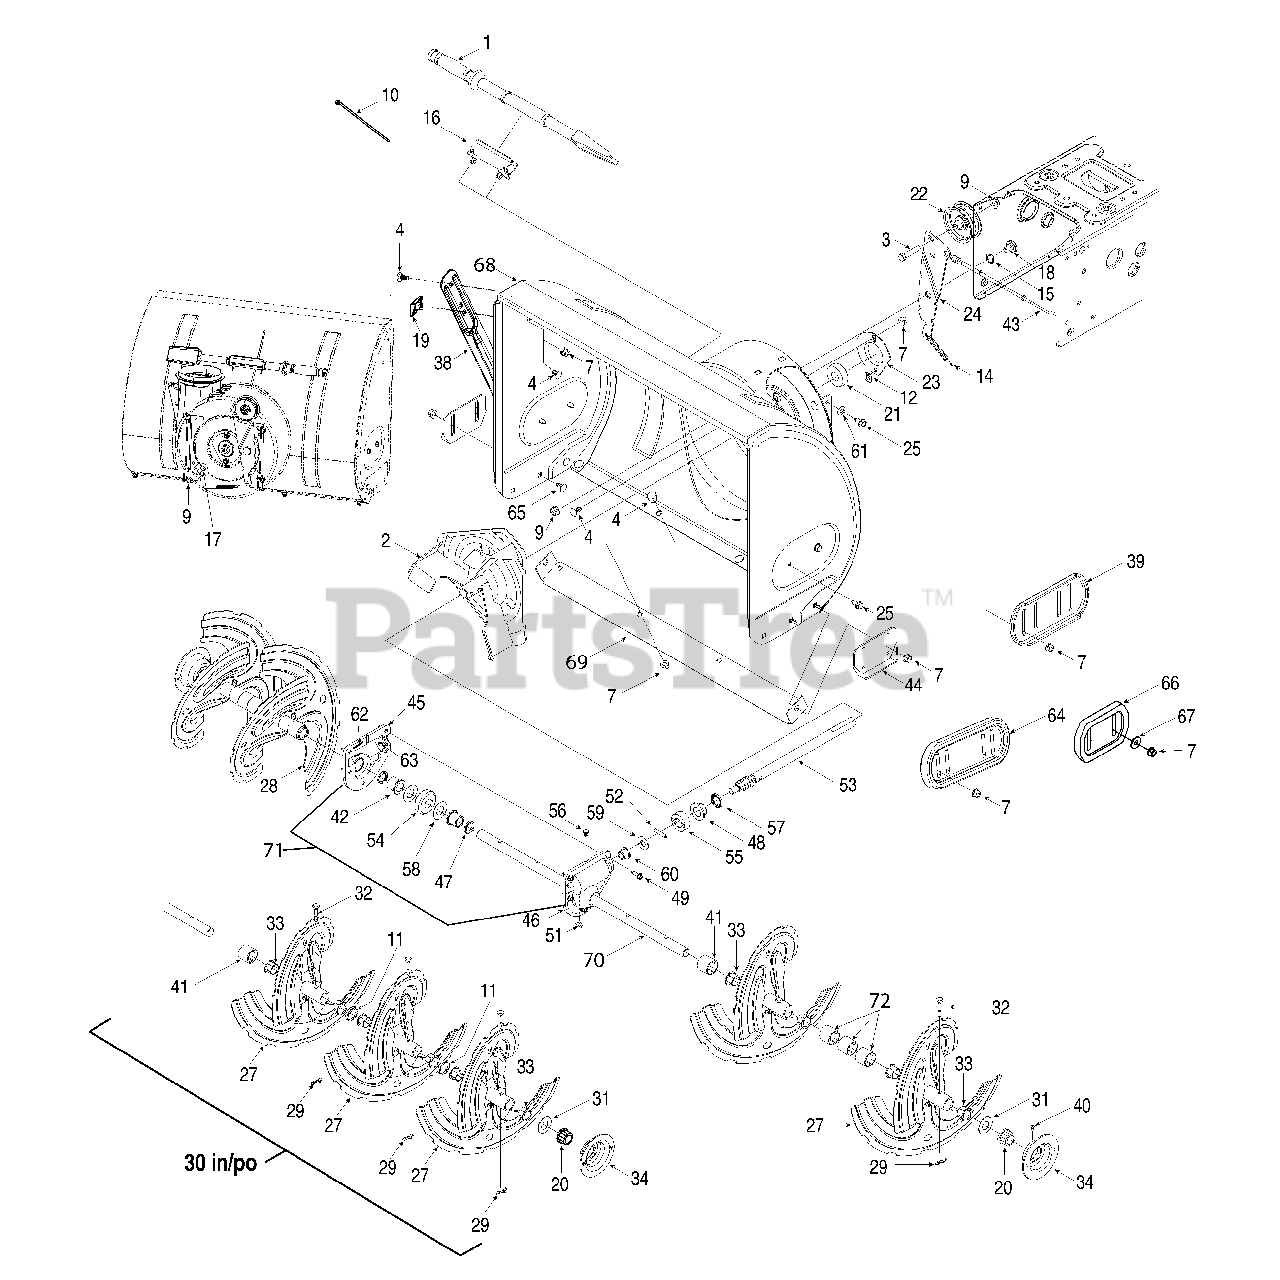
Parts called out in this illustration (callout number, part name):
1	Clean-Out Tool
2	Impeller Ass'y
3	Hex Screw 3/8-16 x 1.75
4	Carriage Bolt 5/16-18 x .75
7	Flange Locknut 5/16-18 Gr. F Nylon
9	Hex L-Flanged Nut 3/8-16 Gr. F Nylon
10	Cable Tie
11	Spacer 1.25 x .75 x 3/16" Lg.
12	Push-on Nut .25 dia.
14	Extension Spring .38 OD x 4.59" Lg.
15	Wave Washer .660 ID x .88 OD x .010
16	Cleanout Tool Mount
17	Shld. Scr. .500 Dia. x .335" Lg.
18	Shoulder Scr .625 Dia x .170
19	Hand Knob
20	Hex. Flange Brg. .751" I.D.
21	Self-aligning bearing
22	Flat Idler Pulley 2.75" OD
23	Bearing Housing 1.85 ID
24	Auger Idler Brake Bracket
25	Hex TT Screw 3/8-16 x .75
27	Spiral Ass'y LH
28	Spiral Ass'y RH
29	Bow Tie Cotter Pin
31	Flat Washer .760 ID x 1.49 OD
32	Shear Pin .25 x 1.5 Gr. 2
33	Flange Bushing
34	Bushing Housing
34	Bushing Housing (w/grease fitting hole)
38	Drift Cutter - Optional
39	Reversible Slide Shoe (steel)
40	Grease Fitting (optional)
41	Spacer 1.25 x .75 x 1.00
42	Flange Bearing.75 ID x 1.0 OD x .975
43	Auger Clutch Cable
44	Slide Shoe
45	RH Reduced Auger Housing
46	LH Reduced Auger Housing
47	Oil Seal .75 x 1.0 x .125
48	Flange Bearing .75 ID x 1.00 OD x .50
49	Thd Forming Scr. 1/4-20 x .75
51	Hi Pro Key 3/16 x 5/8
52	Dowel Pin .25 OD x 1.2
53	Worm Shaft .75 OD
54	Worm Gear 20T (22", 24" & 26")
54	Worm Gear 20T (28" & 30")
55	Thrust Collar
56	Plug, 1/4 x .437
57	Oil Seal .75 x 1 x .131
58	Flat Washer .76 ID x 1.5 OD x .03
59	Fl. Washer .510 x 1.120 x .060
60	Flange Bearing .75 ID x 1.0 OD x .925
61	Cupped Washer .345 ID x .88 OD x .060
62	Loctite Sealant 5699
63	Grease - Alvania EP Lead Free
64	Reversible Slide Shoe, Polymer
64	Deluxe Polymer Reversible Shoe Kit
65	Carriage Bolt 5/16-18 x .75 (w/steel slide shoes)
65	Carriage Bolt 5/16-18 x 1.0 (w/ polymer slide shoes)
66	Small/Standard Polymer Reversible Slide Shoe
66	Standard Polymer Reversible Shoe Kit
67	Flat Washer .349 ID x .879 OD x .063
68	24"Auger Housing Majestic Orange
68	26"Auger Housing Majestic Orange
68	28"Auger Housing Majestic Orange
68	30"Auger Housing Majestic Orange
69	24" Shave Plate Majestic Orange
69	26" Shave Plate Majestic Orange
69	28" Shave Plate Majestic Orange
69	30" Shave Plate Majestic Orange
70	24" Auger Axle
70	26" Auger Axle
70	28" Auger Axle
70	30" Auger Axle
71	24" Gearbox Assembly
71	26" Gearbox Assembly
71	28" Gearbox Assembly
71	30" Gearbox Assembly
72	Spacer 1.25 x .75 x 1.00
72	Spacer 1.25 x 75 x 2.00
